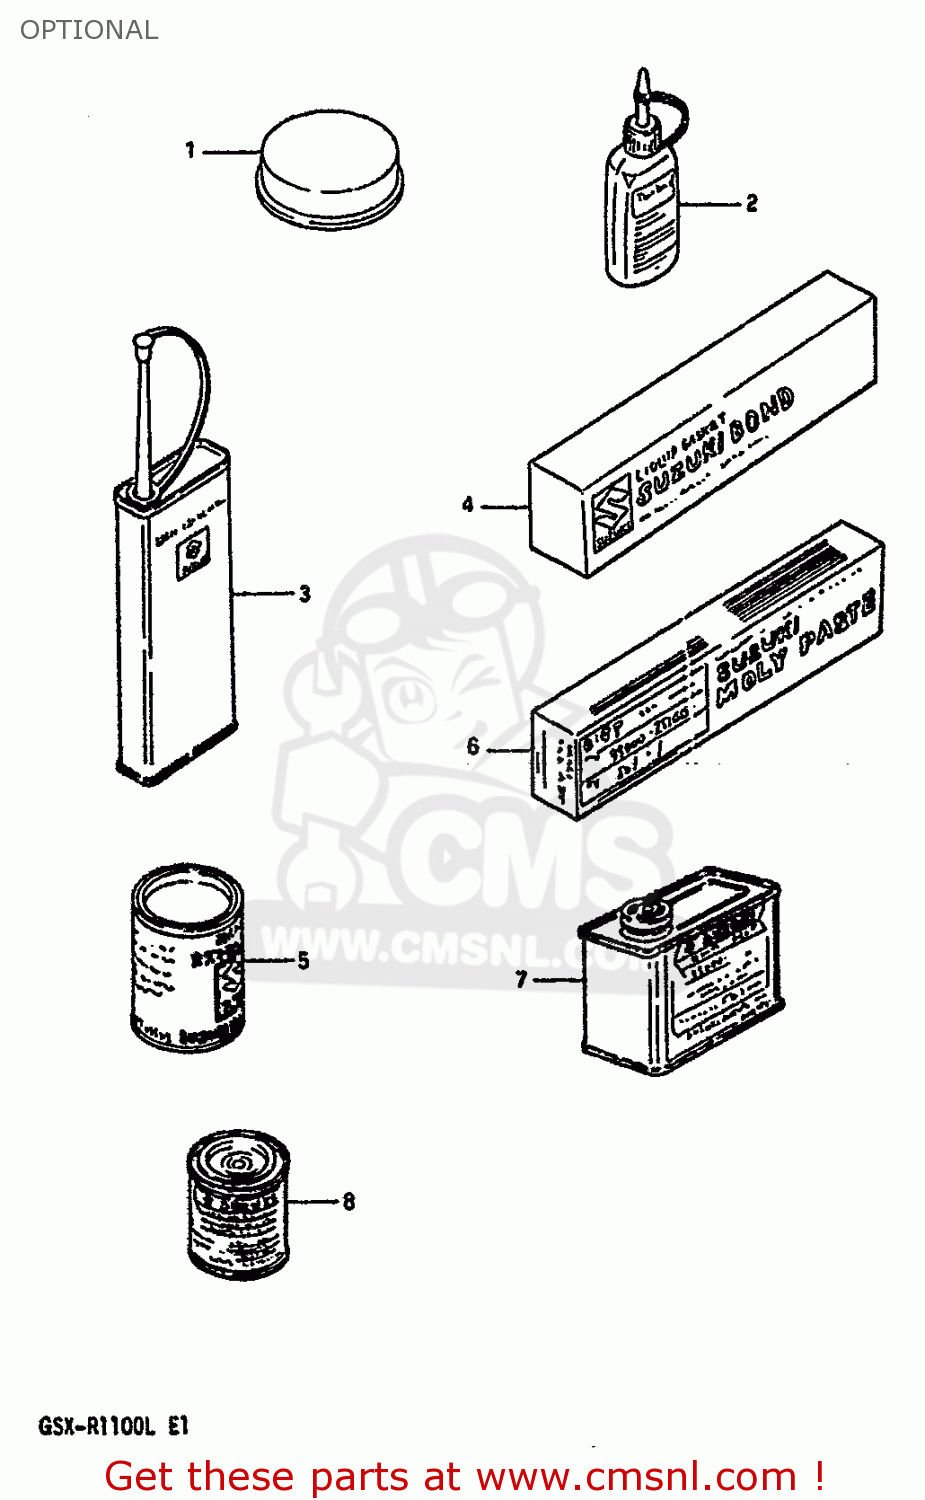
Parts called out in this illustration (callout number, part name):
1	GREASE,PBC FOR BRK PAD 20G
2	THREAD LOCK NO.1342
3	THREAD LOCK NO.1401 CLEAR 200G
4	LIQUID GSKT NO.1207B 100G BLK
5	GREASE(C)EP2 LITHIUM 150G
6	SUZUKI MOLY PASTE
7	PAINT (PARSEC BLUE)
8	PAINT (PARSEC BLUE)
